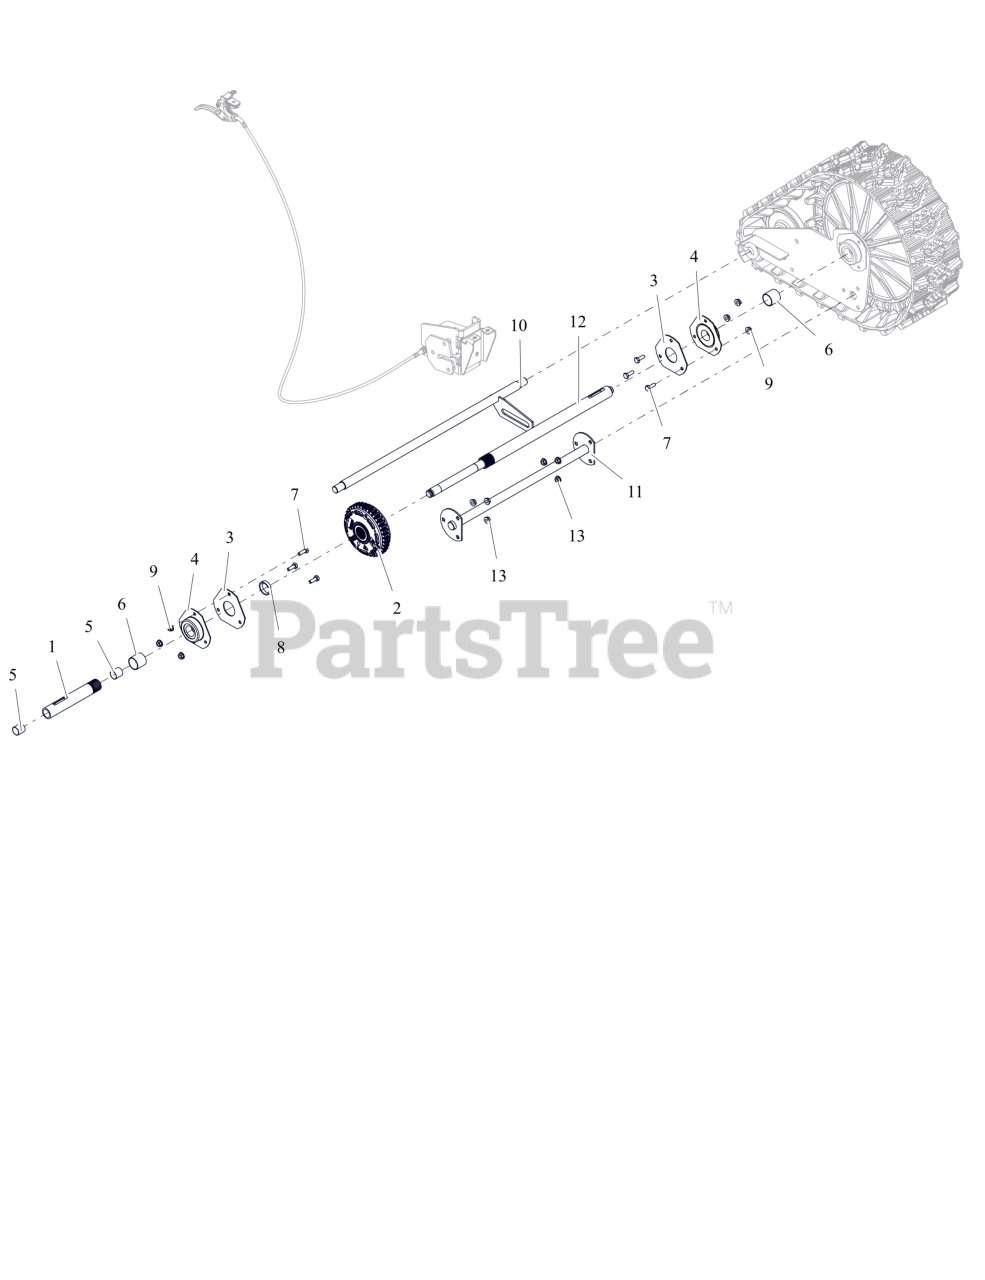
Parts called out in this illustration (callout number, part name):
1	AXLE, SHORT-W/BUSHINGS
2	DIFFERENTIAL, AUTOMATIC
3	PLATE, BEARING SPACER
4	BRG-FLG 1.003/1.000 3 BOLT
5	BSHG-SLV .706X.764X.75 BRZ
6	BSHG-SLV, 1.012X1.125X1.00
7	BLT, HEX .25-20X.75 G5 ZCC
8	BSHG, SLV 1.062X1.228X.268
9	NUT-LK-CTR-FLG .25-20 ZC120
10	AXLE, REAR-BWT WLDMT
11	SUPPORT, FRONT-BWT
12	AXLE, LONG-TRACK DIFFERENTIAL
13	NUT-LK-TOP-FLG .250-20 GF ZCC
